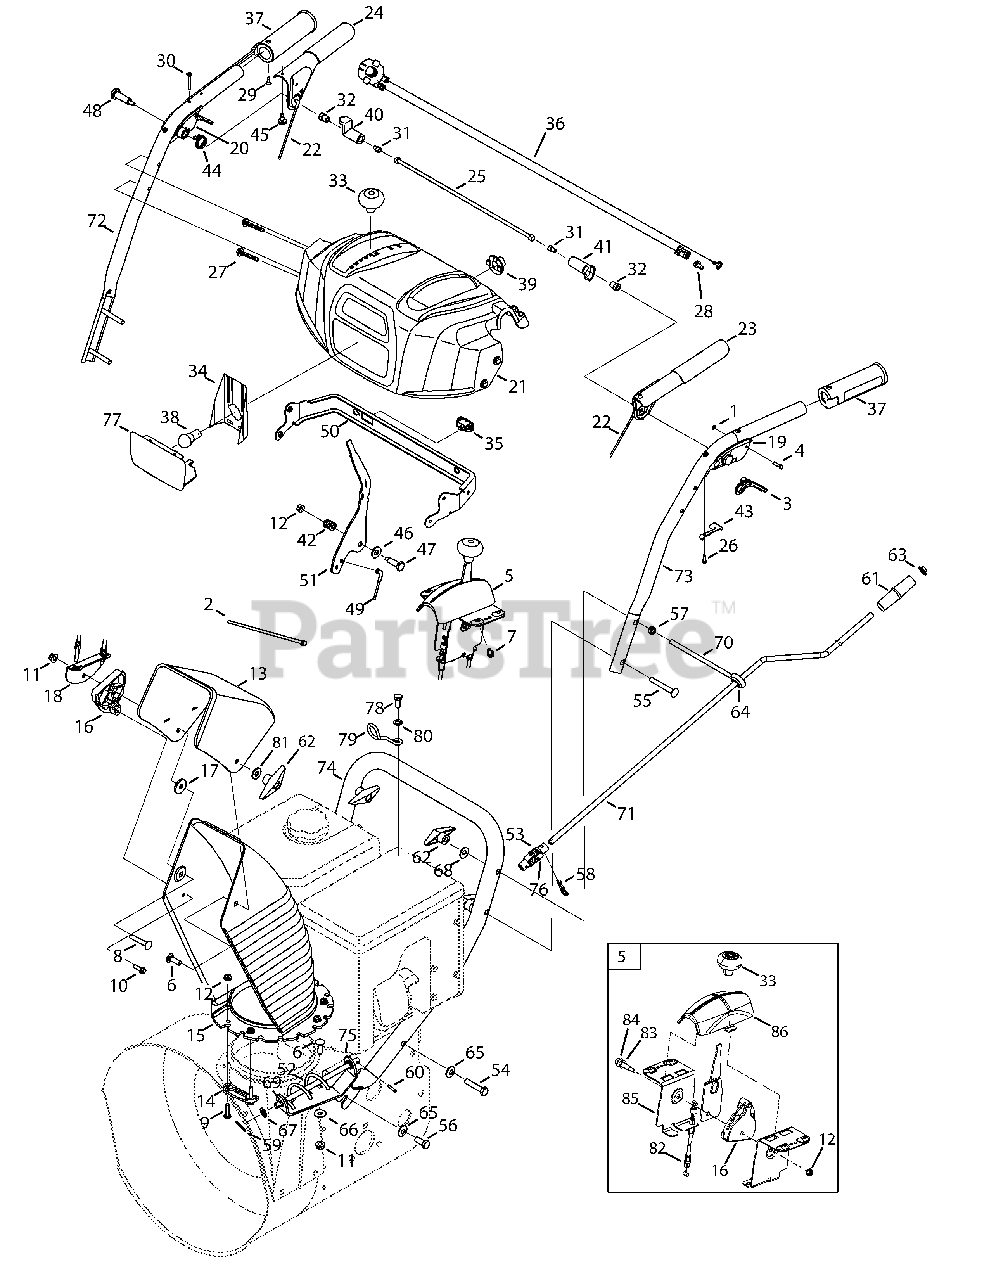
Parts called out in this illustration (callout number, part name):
2	Cable Tie
3	Trigger Lock
5	Chute Control Assembly
6	Carriage Screw, 5/16-18 x 1.0
7	Screw, 1/4-15 x .50
8	Carriage Screw, 5/16-18 x 1.75
9	Hex Screw 1/4-20 x 1.0
10	Screw, 1/4-15 x .750
11	Flange Lock Nut 5/16-18
12	Flange Lock Nut 1/4-20
13	Upper Chute, 6.0
14	Chute Flange Keeper
15	Lower Chute
16	Cbl. Guide, Chute Tilt
17	Flat Wash, .344 x 1.125 x .12
18	Cable Bracket
19	Handle Assembly, LH
20	Handle Assembly, RH
21	Handle Panel
22	Cable Ass’y, Auger/Drive
23	Engagement Handle, LH
24	Engagement Handle, RH
25	Clutch Lock Rod Assembly
26	Screw, #8-16 x .50
27	Screw, 1/4-20 x 1.625
28	Hex Screw, 1/4-20 x .5
29	Screw, #10-16 x .625
30	Screw, #10-24 x 1.375
31	Screw, 1/4-20 x .50
32	Nut, Hex, 1/4-20
33	Shift Knob
34	Lens Lable
35	Heated Grip Switch
36	Wire Harness
37	Heated Grip
38	Lamp, 12.8V
39	Light Socket
41	Clutch Lock Cam
42	Compression Spring
43	Clutch Lock Spring
44	Torsion Spring, .8156 ID x .3038
45	Rubber Bumper
46	Flat Washer, .385 x .87 x .06
47	Screw, Shldr., .374 x 1.05
48	Screw, Shldr., .437 x 1.345
49	Clutch Cable
50	Panel Bracket
52	Chute Crank Assembly
53	Joint Block Assembly
54	Hex Screw, 3/8-16 x 2.00
55	Carriage Screw, 5/16-18 x 2.5
56	Screw, Hex, 3/8-16 x 1.00
57	Nut, Hex, 5/16-18
58	Internal Cotter Pin
59	Pin, Bow-tie Cotter
60	Spring Pin, .156 dia. x .875 Lg.
61	Knob, Crank
62	Knob, Wing Nut, 5/16-18
63	Push Cap, 3/8
64	Rubber Grommet
65	Bell Wash, .375 x .87 x .063
66	Flat Washer, .349 x .879 x .063
67	Flat Wash, .375 x .738 x .063
68	Wash, Bell, .34 x .872 x .06
69	Plastic Bushing, .38 ID
70	Eye Bolt, .70 Dia.
71	Chute Rod, .375 Dia. x 29.72
72	Handle, Upper, RH
73	Handle, Upper, LH
74	Handle, Lower
75	Chute Crank Bracket
76	Roll Pin, 3/16 Dia. x 1.100
78	Hex Screw, M8-1.25
79	Cable Guide
80	Flat Washer, .330 x .630 x .0635
81	Washer, Flat, .349 x .879
82	Cable, Chute Tilt
83	Washer, Spring, .39 x .625 x .012
84	Screw, Shoulder, .31 x .995:1/4-20
85	Bracket, Mounting
86	Cover, Tilt Cover
